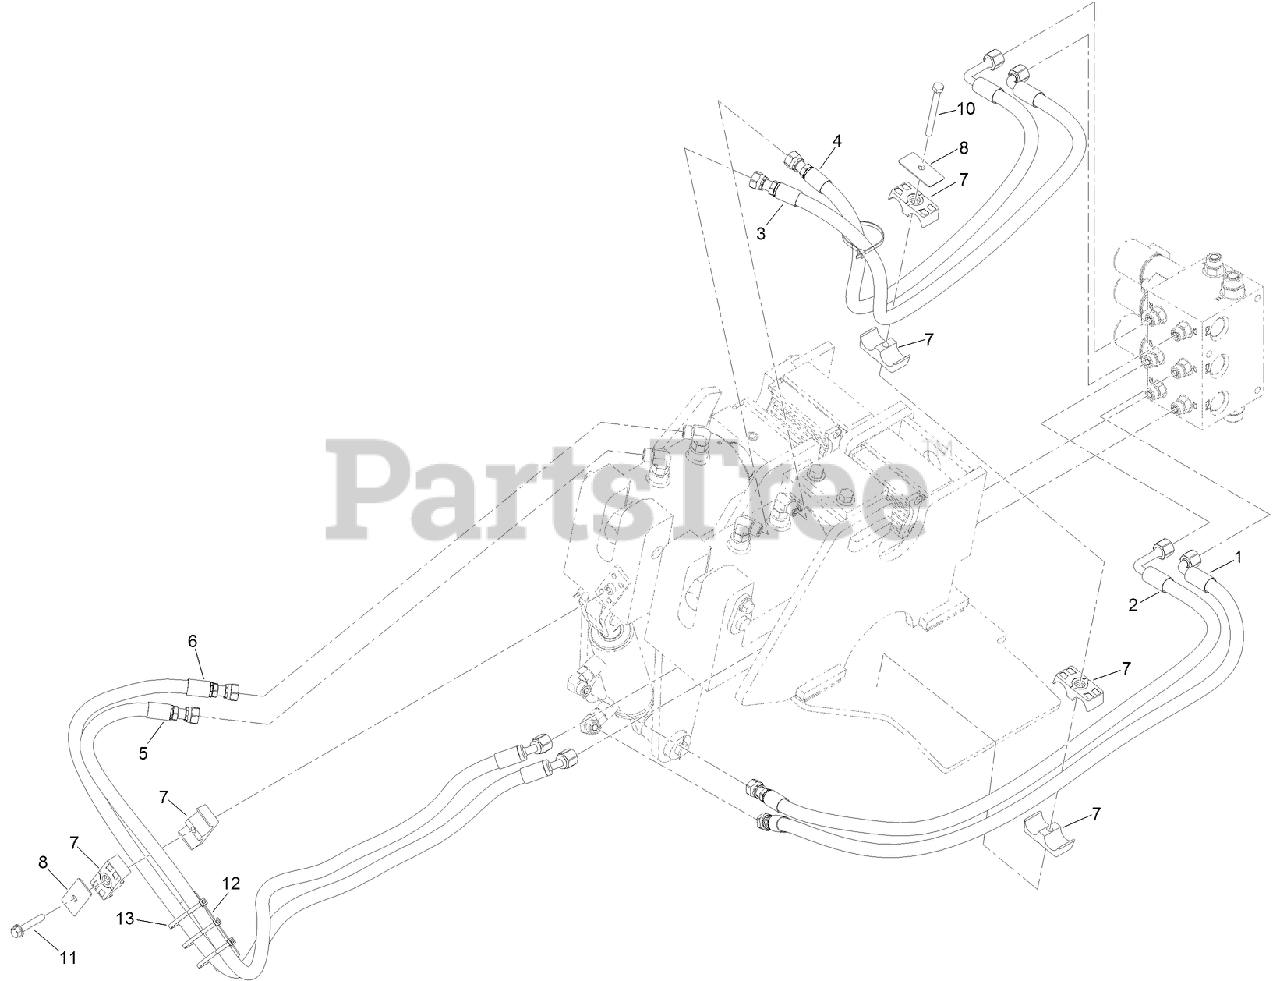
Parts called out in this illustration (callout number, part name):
1	HOSE-HYD
2	HOSE-HYD
3	HOSE-HYD
4	HOSE-HYD
5	HOSE-HYD
6	HOSE-HYD
7	CLAMP-TUBE
8	PLATE-COVER
10	SCREW-HH
11	SCREW-HWH
12	PROTECTOR-HOSE
13	TIE-CABLE
